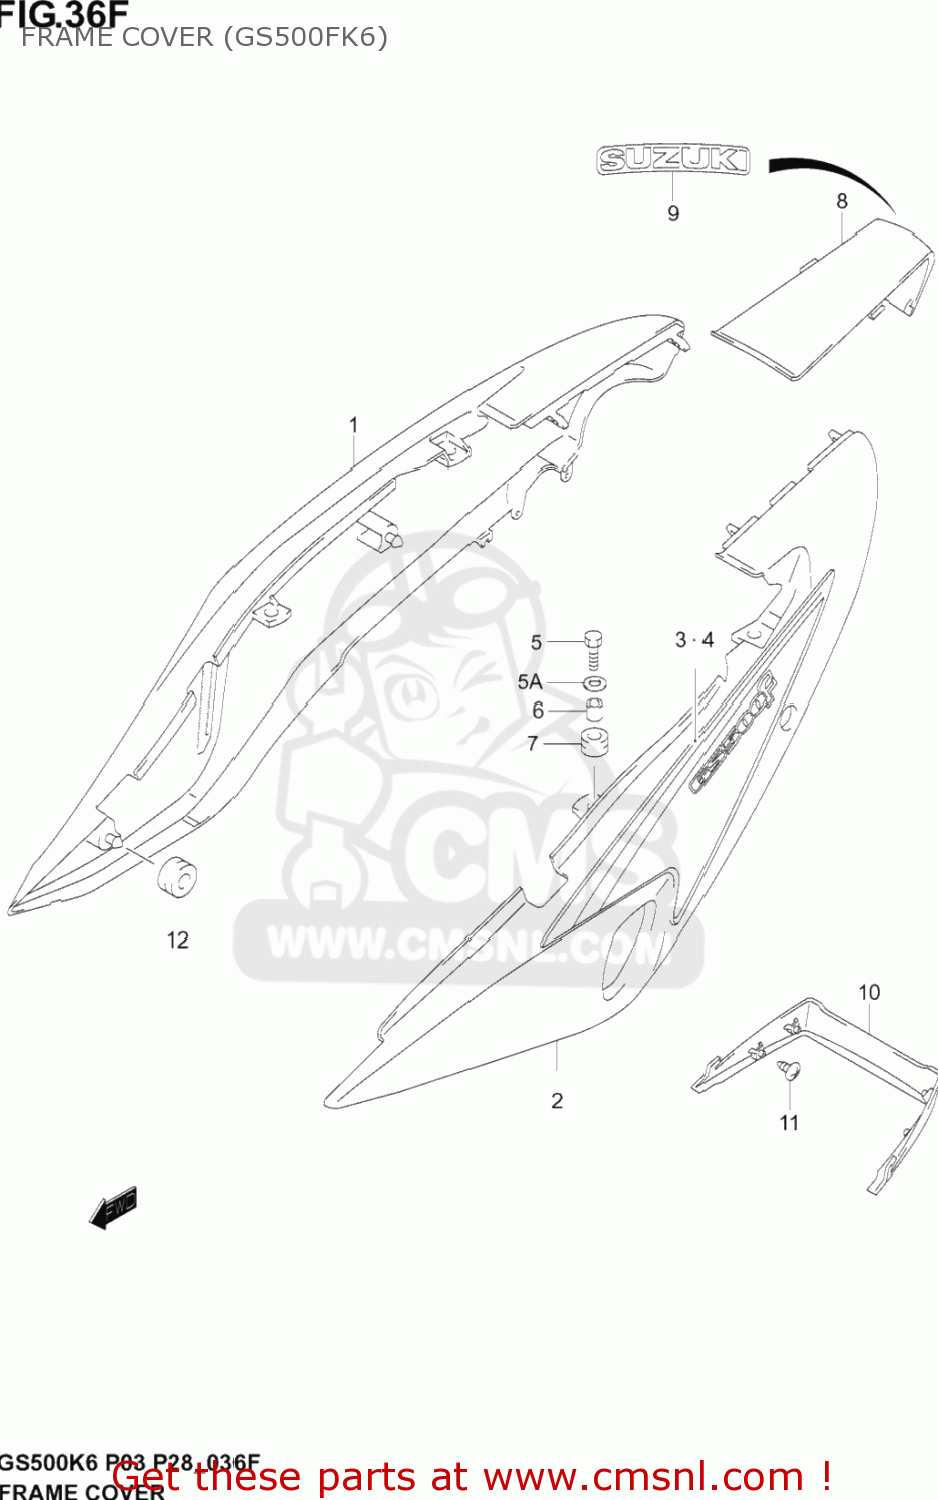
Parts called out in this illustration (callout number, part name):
1	COVER,FRAME RH
2	COVER,FRAME LH
3	EMBLEM SET RH
4	EMBLEM SET RH
5	BOLT
5A	WASHER
6	SPACER(6.5X9X9)
7	CUSHION
8	COVER,CENTER
9	EMBLEM (BLACK)
10	COVER LOWER
11	SCREW
12	CUSHION
